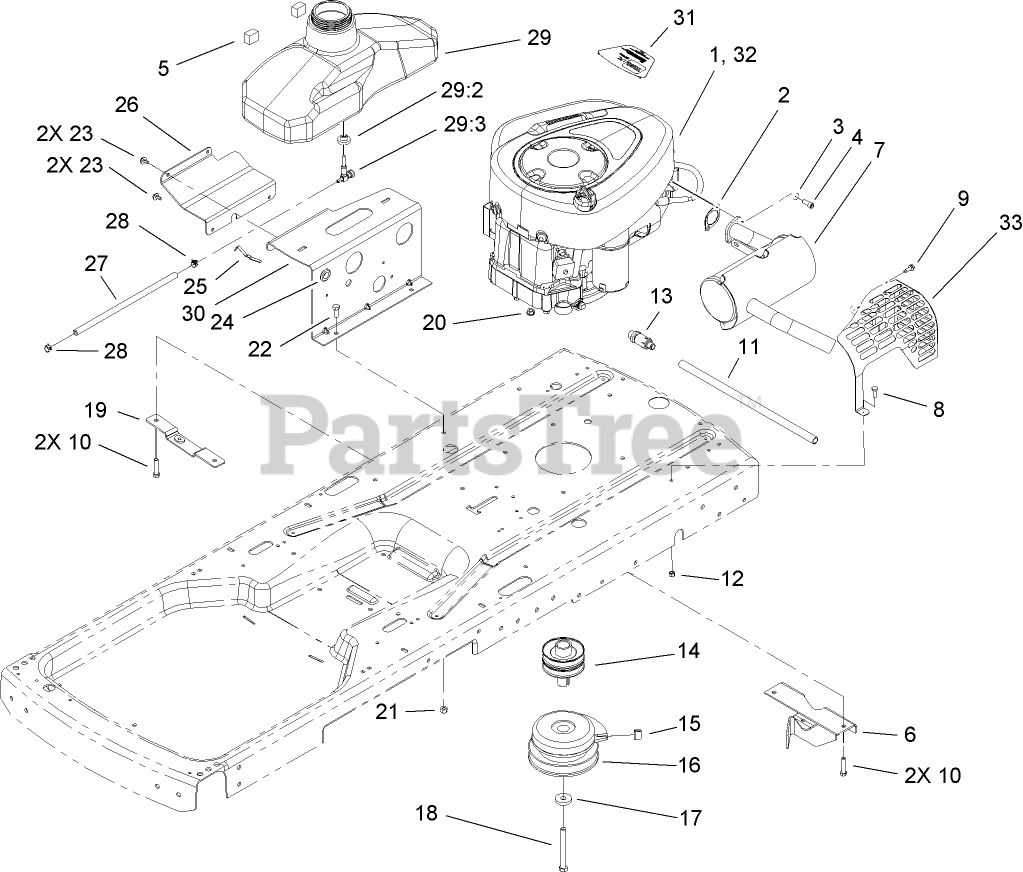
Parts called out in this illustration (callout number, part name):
1	Loose Parts Package
2	GASKET-EXHAUST
3	WASHER-LOCK
4	SCREW-HSH
5	FOAM-SWITCH, SEAT
6	BRACKET-PIVOT
7	MUFFLER
8	SCREW-HH
9	SCREW-HWH, THREAD ROLL
10	SCREW-HH
11	TUBE-DRAIN, OIL
12	NUT-LOCK, NI
13	VALVE-DRAIN, OIL
14	PULLEY-ENGINE
15	BUMPER
16	CLUTCH-ELECTRIC
17	WASHER
18	SCREW-HH
19	PLATE-MOUNT, IDLER
20	NUT-HF
21	NUT-LOCK, NI
22	SCREW-HH
23	SCREW-HHFTF
24	GROMMET
25	SPRING
26	PLATE-SUPPORT
27	HOSE-FUEL
28	CLAMP-HOSE
29	GAS TANK ASM
29:2	BUSHING
29:3	VALVE-FUEL
30	PLATE-TANK
31	DECAL-ENGINE
32	REDUCER-THROTTLE, RPM
33	GUARD-MUFFLER
